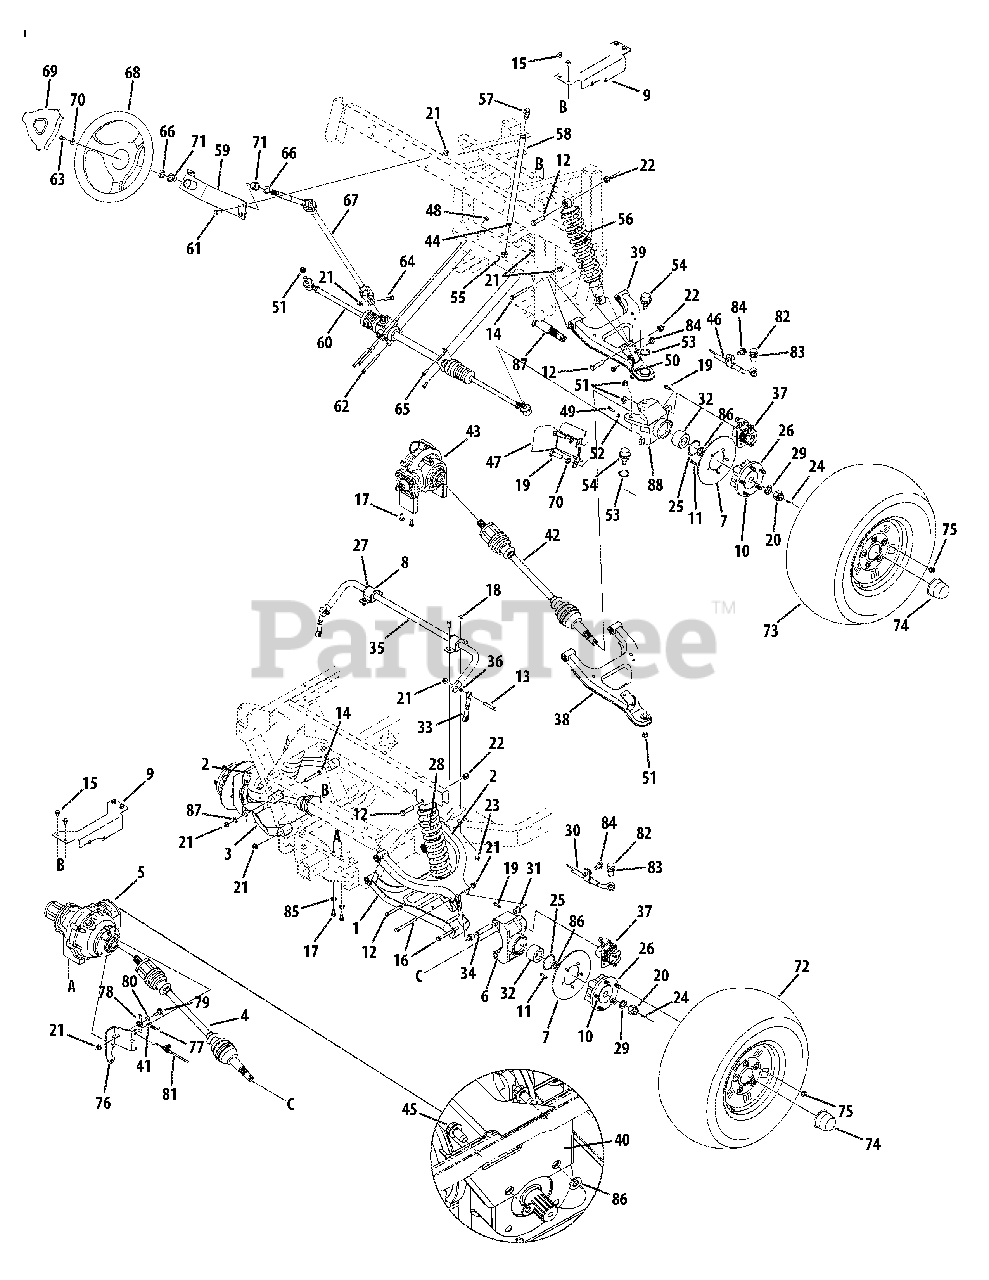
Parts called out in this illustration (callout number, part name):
1	Cont Assembly, lwr, r/rr
2	Cont Assembly, rr Upr
3	Cont Assembly, lwr, l/rr
4	Axle Assembly, cv Joint
5	Diff Assembly, Uv, complete
6	Hsg, rr, mach
7	Disc, brake, 8.00x.188
8	Mt, sway Bar
9	Mt, rear/diff, 4x4
9	Mt,front/diff, 4x4
10	Stud, rib Neck, 7/16-14 X 1.6
11	Screw, 1/4-20, .625, gr5, lock
12	Screw, 1/2-13, 2.00, gr5, std
13	Screw, 3/8-18, 1.75, gr5
14	Screw, 3/8-16, 3.00, gr8, std
15	Scr, tt, 5/16-18, 0.500, hxindwsh
16	Screw, 3/8-16, 4.00, gr5
17	Screw, 3/8-16, .75, gr5, std
18	Screw, 5/16-24, .75, gr5, std
19	Screw, m8-1.25, 25.00
20	Nut, slotted, 22x1.5
21	Nut, flglk, 3/8-16, grf, nylon
22	Nut, hexlk, 1/2-13, grb, nylon
23	Nut, flglk, 5/16-18, grf, nylon
24	Pin, cot, 5/32, 1.25
25	Ring, ret, dho-60
26	Hub, Wheel
27	Bush, sway Bar
28	Shabs, 5.0 Stroke, rr
29	Wash, flat, .88 X 1.38 X .125, ht
30	Hose, brake, rear
31	Brg, flg, .625 X .750 X .750 Lg
32	Brg, dble Row, 60x30x37
33	Rod, cont, .375x3.886
34	Tube, pivot, rr/cont Arm
35	Bar, sway, rr
36	Washer, Flat, .407 x .812 x .135
37	Brake, hyd, caliper RH
37	Brake, hyd, caliper LH
37	Brake Pad Kit
38	Cont Assembly,r/frt,lwr
39	Arm Assembly,r/frt,upr
40	Brkt, Diff, RR
42	Axle Assembly,cv Joint,4x4
43	Diff Assembly,cfd,4x4
44	Clamp, Hose, Adj.
45	Scr., tt, 3/8-16 x .750
46	Hose, brake, front
47	Brkt,shld,strg,RH
48	Nut, Flg Lk, 5/16-18
49	Screw,1/4-20,1.00,gr5,spec
50	Wire, Brake Line
51	Nut,nylock,m12x1.25
52	Nut,hex,1/4-20,gr5
53	Ring,ret,34x1.6
54	Ball joint, bj14d-6201
55	Clamp,hose,.490 Dia.
56	Shabs,5.0 Stroke,frt
57	Vent,3/8 Dia
58	Hose,fuel Line
59	Supt Assembly,strg,Wheel
60	Strg Assembly,gr
61	Screw,3/8-16,1.00,gr5,std
62	Screw,5/16-18,3.50,gr5,std
63	Screw,5/16-18,.75,gr5,patch
64	Screw,3/8-16,1.25,gr5,std
65	Screw,5/16-18,.75,gr5,std
66	Ring,e Type,.750
68	Wheel,strg,soft Grip 3 Spoke 5/8
69	Cvr, Wheel, steering
70	Wash,bell,.340 X .872 X .060
71	Brg,flg,.754id X 1.00odx.925
72	Wheel Ass’y, Right compl,25x11-12, AT, Beige
72	Wheel Ass’y, Right compl,25x11-12, AT, black
72	Wheel Ass’y, Right compl,25x11-12, AT, Spoke
72	Wheel Ass’y, compl,25x10-12, All Trail, black
73	Wheel Ass’y, Right compl,25x10-12, AT, Beige
73	Wheel Ass’y, Right compl,25x10-12, AT, black
73	Wheel Ass’y, Right compl,25x10-12, AT, Spoke
73	Wheel Ass’y, compl,25x10-12, All Trail, black
74	Cap, Wheel UV
74	Cap, Wheel UV, Chrome
75	Nut, lug, 7/16-14
75	Nut, lug, 7/16-14, Chrome
76	Brkt, diff, cbl,mnt
77	Spr, ext, .38od x 2.10
78	Lvr, Ass’y, Diff Lock
79	Scr, shldr, .500 dia x .434
80	Brg, flg, nyliner, .500id x .34lg
81	Cbl, cont, diff, lock
82	Ftg, banjo ftg bolt, M10x1.00
83	Ftg, banjo ftg crush wash,10mm
84	Screw, tt, 1/4-20x.500
85	Washer, Flat, .385 x .870 x .092
86	Wash, Flat, .344 x .688 x .065
87	Axle, Frt, 4x2
88	Hsg,knuckle,r/frt,mach
